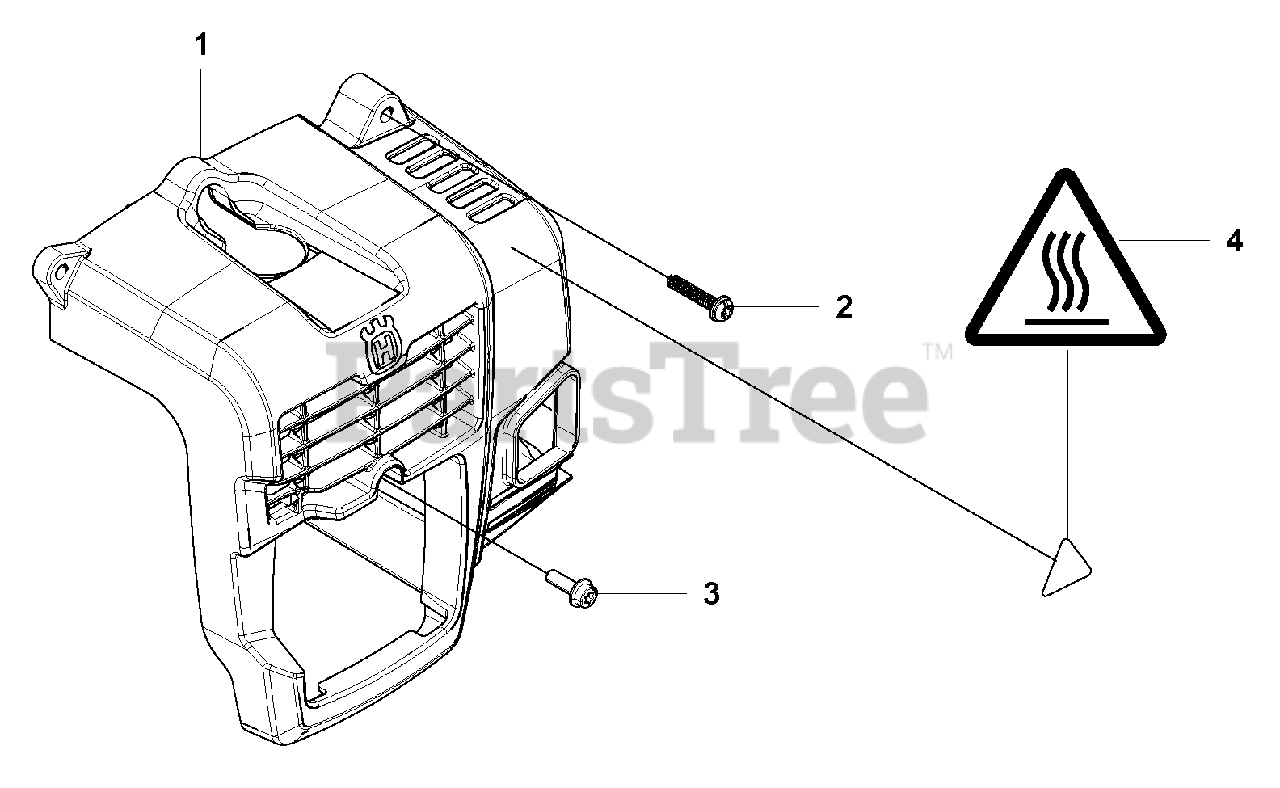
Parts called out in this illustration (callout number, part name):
1	ENGINE COVER
2	SCREW
3	BOLT
4	RP_LABEL, HOTMARK
